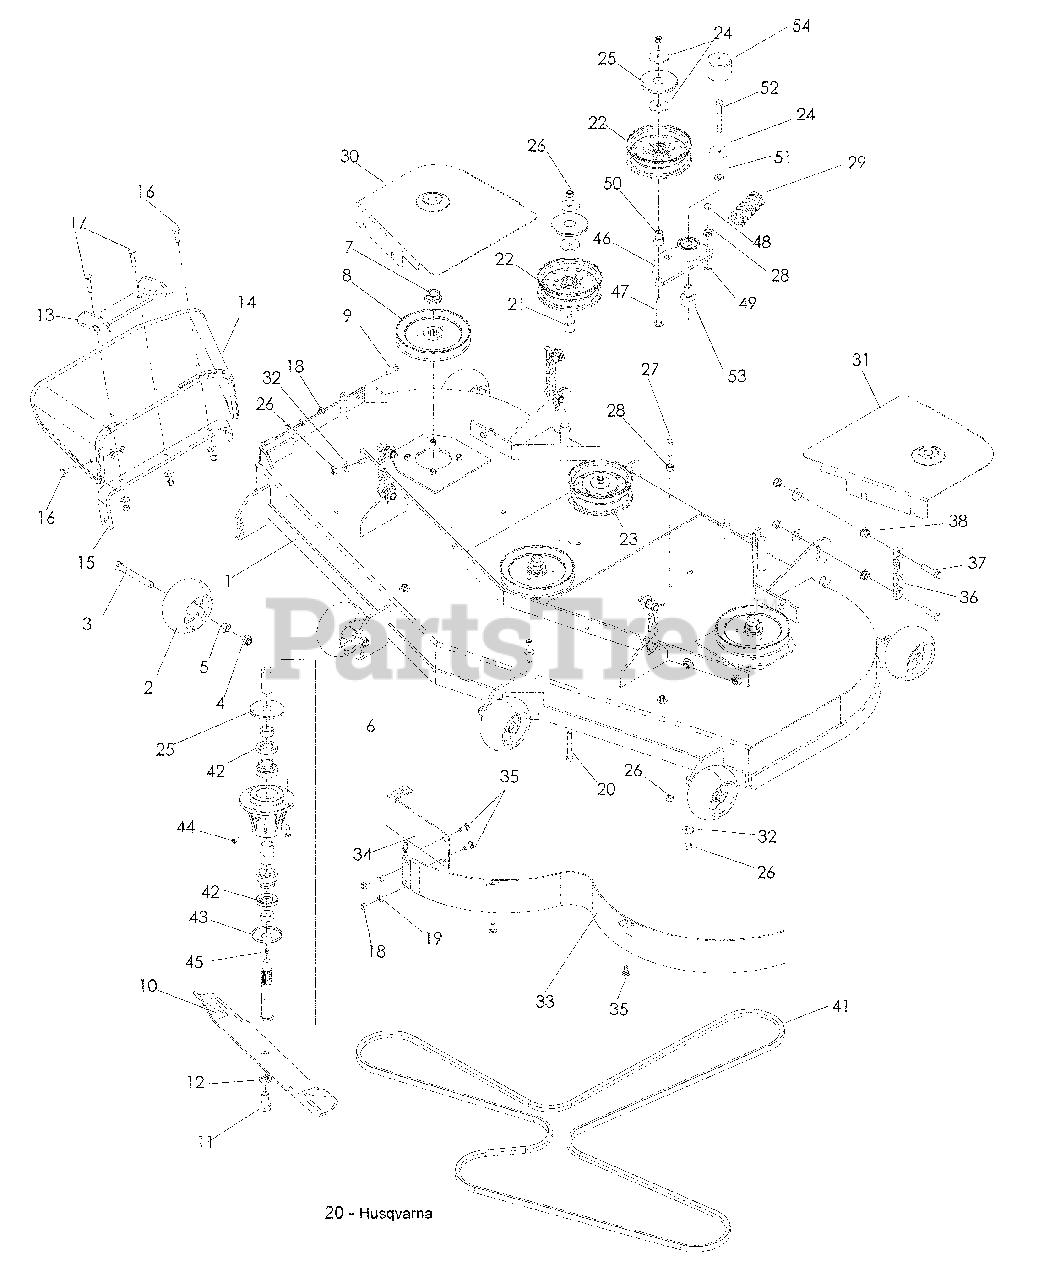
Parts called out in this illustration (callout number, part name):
1	DECK W/DECALS
2	WHEEL, GAUGE
3	HCS ½-13 x 4
4	NUT ½-13 HEX NYLOC
5	NUT ½-13 HEX
6	HOUSING ASSM, 52/61
7	NUT, FLANGE ¾-16
8	PULLEY, 61
9	HCS 5/16-18 x 1¼
10	BLADE, 21"
11	HCS 5/8-18 x 1¼
12	WASHER 5/8 SLW
13	PIVOT BRACKET, CHUTE
14	RUBBER CHUTE, 52/61
15	BRACKET, REINFORCE
16	RHSNB 5/16-18 x 1¼
17	RHSNB 5/16-18 x 1½
18	NUT 5/16-18 HEX NYLOC
19	WASHER 5/16 STD FLT
20	HCS 3/8-16 x 2¾
21	BUSHING, IDLER
22	IDLER PULLEY
23	IDLER PULLEY
24	WASHER 3/8 SPECIAL
25	TOP DUST CAP
26	NUT 3/8-16 HEX NYLOC
27	HCS 3/8-16 x 1¼
28	NUT 3/8-16 HEX WHIZLK
30	61 BELTSHIELD RT.
31	61 BELTSHIELD LT
32	WASHER 3/8 STD FLT
33	BAFFLE MAIN
34	BAFFLE CENTER
35	RHSNB 5/16-18 x ¾
36	LIFT CHAIN
37	HCS 7/16-14 x 1¾
38	NUT 7/16-14 HEX WHIZ LK
39	WASHER 7/16 FLAT
40	NUT 7/16-14 HEX NYLOC
41	BELT, DECK 61"
42	SHAFT SEAL
43	BOTTOM DUST CAP
44	GREASE POPPET
46	ARM, IDLER - W/BEARINGS
47	RHSNB 3/8-16 x 2¾
48	HCS 3/8-16 x 1½ GR 8
49	NUT 3/8-16 HEX JAM
50	BUSHING, IDLER
51	WASHER 3/8 SAE FLT
52	HCS 3/8-16 x 3
53	PIVOT, BEARING
54	CAP, VINYL
